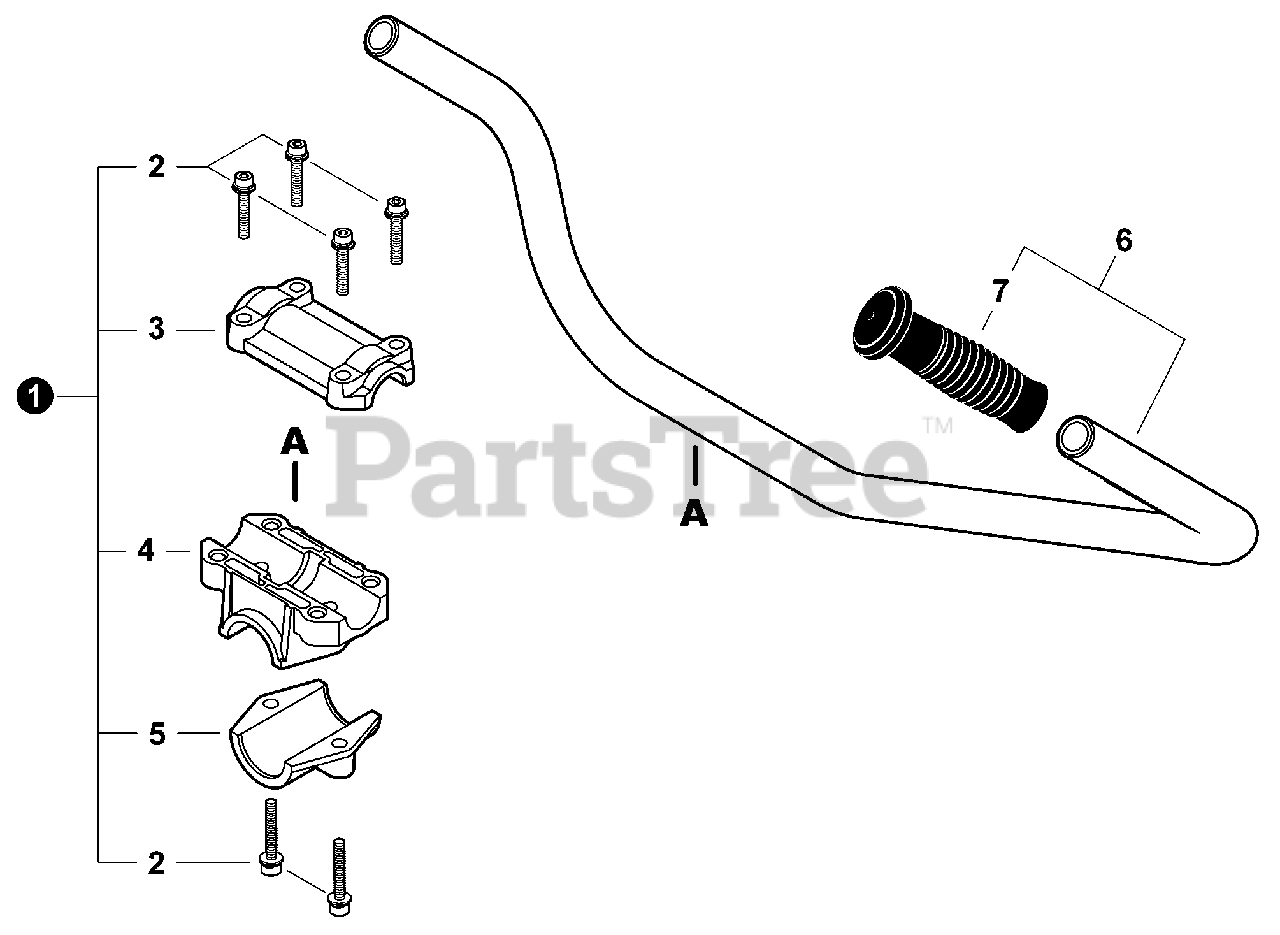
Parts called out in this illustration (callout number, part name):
1	BRACKET KIT, HANDLEBAR
2	BOLT M5×25
3	BRACKET, UPPER HANDLEBAR
4	BRACKET, LOWER HANDLEBAR
5	BRACKET, MOUNTING
6	HANDLEBAR ASSY
